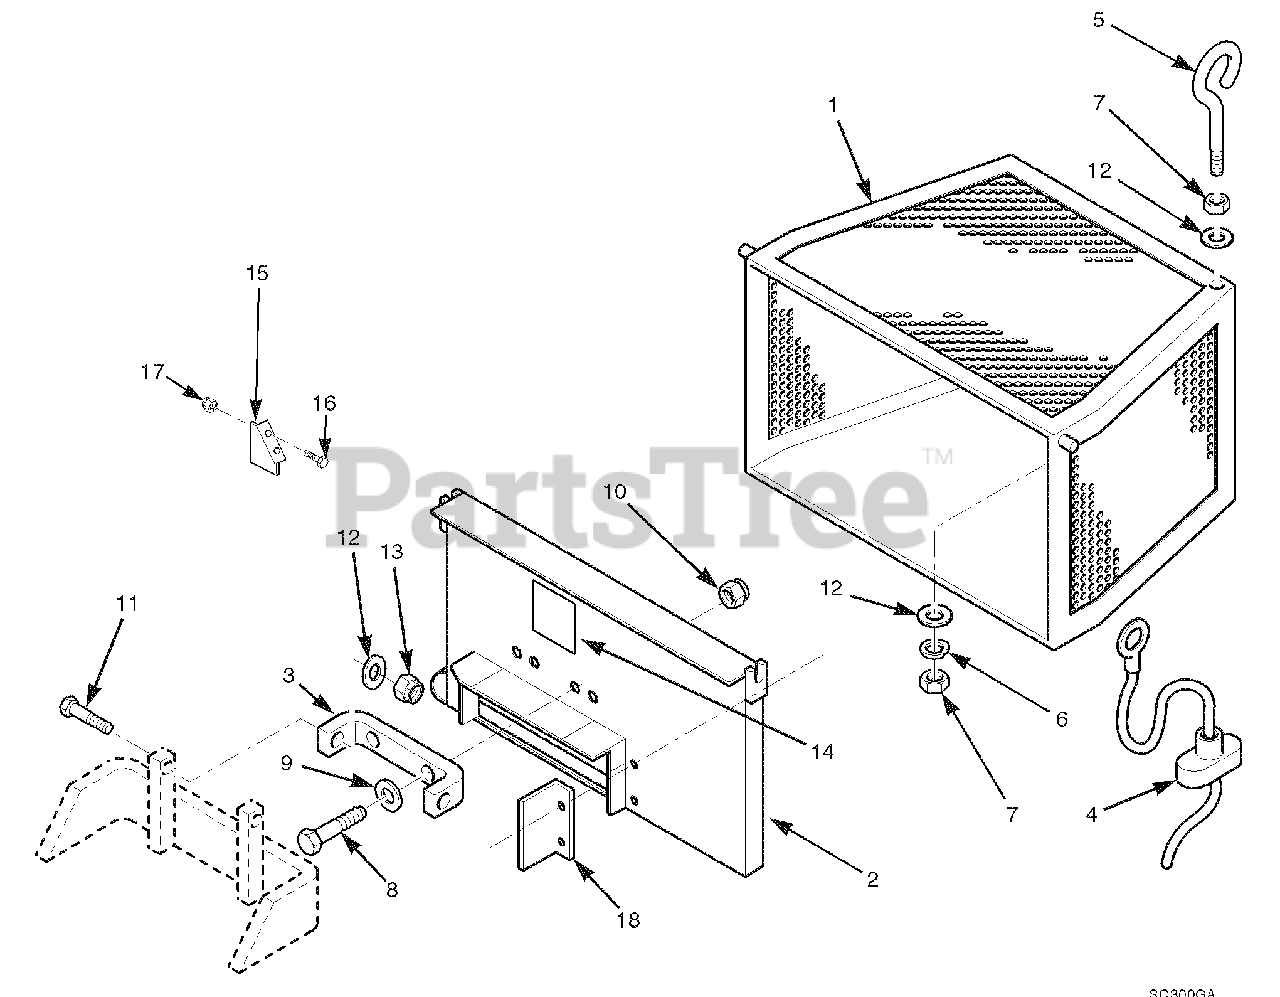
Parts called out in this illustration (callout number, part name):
1	Catcher Box
2	Cover Weldment W/Decal
3	Mounting Bracket
4	Pull Rope Assembly
5	Eyebolt, 5/16-18 x 2-1/4"
6	Lock Washer, 5/16"
7	Nut, 5/16-18 Hex Head
8	Bolt, 3/8-16 x 1-1/2" Hex Head
9	Flat Washer, 3/8"
10	Nut, 3/8-16 Elastic Stop
11	Bolt, 5/16-18 x 1-1/4" Hex Head
12	Flat Washer, 5/16"
13	Nut, 5/16-18 Elastic Stop
14	Decal, Danger
15	Filler Plate, Chute Advantage Deck Only
16	Bolt, Hex Head 1/4-20 x 3/4"
17	Nut, Elastic Stop 1/4-20
18	Filler Plate, Grass Catcher Advantage Decks
